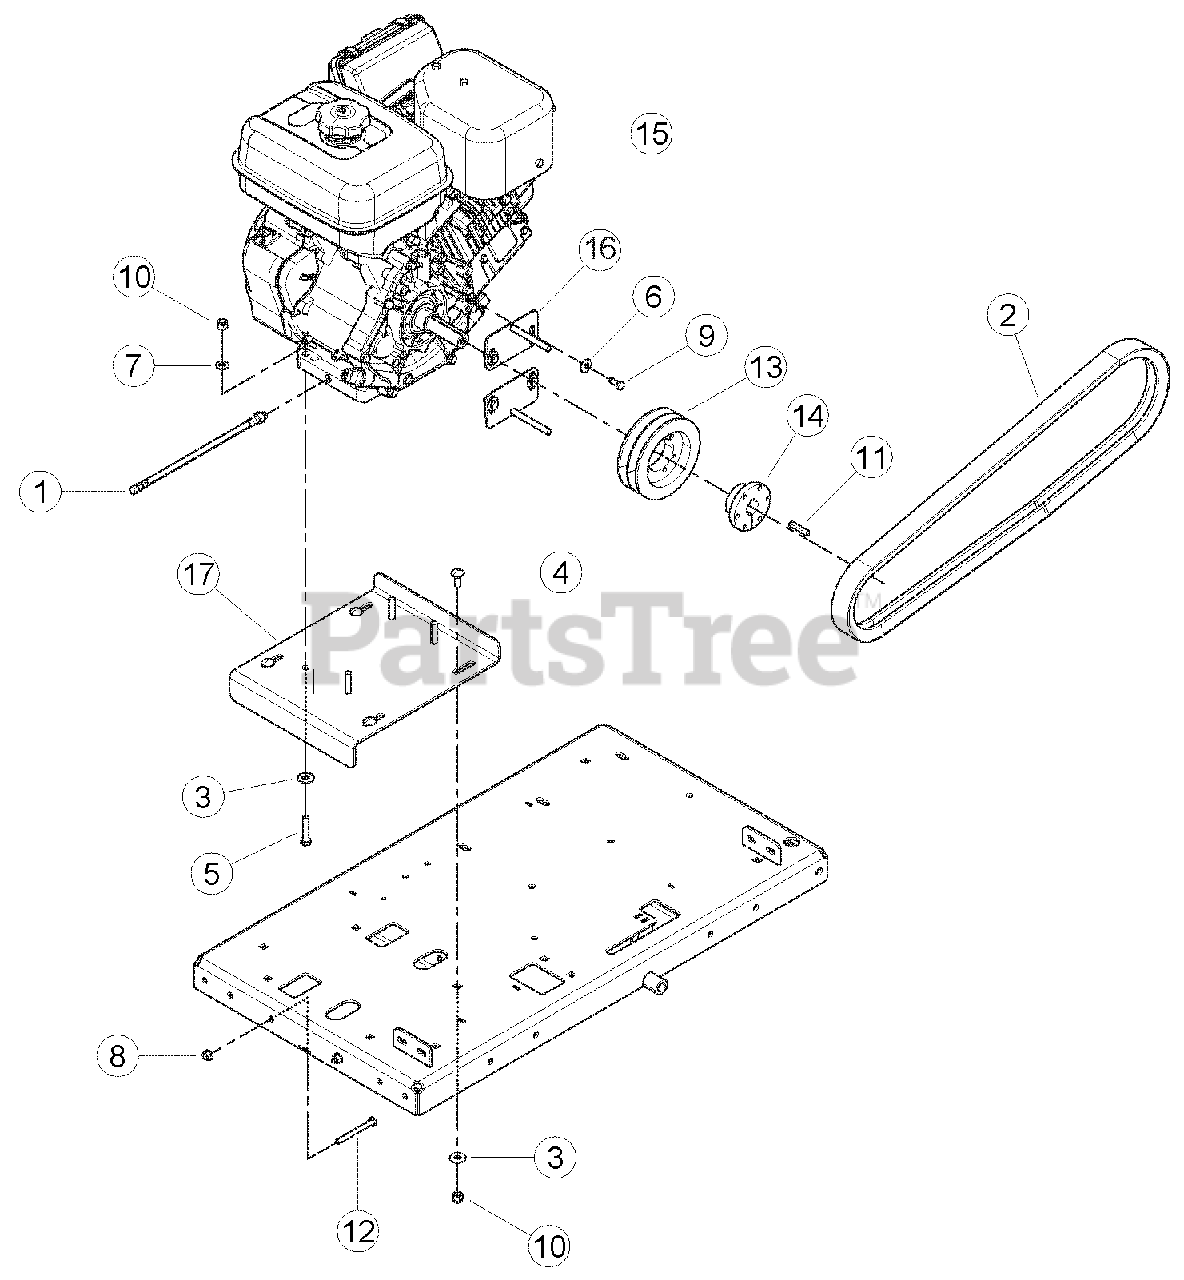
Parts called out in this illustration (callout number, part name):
1	HOSE ASSY, CRANKCASE DRAIN
2	BELT, 2RB61 ARAMID
3	WASHER, 3/8 FLAT ZP
4	BOLT, 3/8 X 1 CRG GR5 NC ZP
5	BOLT, 3/8 X 1-3/4 HCS GR5 ZP
6	WASHER, 5/16 FLAT ZP
7	WASHER, 3/8 SAE FLAT ZP
8	NUT, 5/16 SERR FLANGE NC ZP
9	BOLT, 5/16-24 X 3/4 HHCS GR5 ZP
10	NUT, 3/8 NE NYLOCK ZP
11	KEY, 1/4 SQUARE X 1-1/2 LONG PLAIN
12	BOLT, 5/16 NC X 3 FULL THD (CH4400)
13	SHEAVE, 2B5.2 SDS
14	BUSHING, SDS 1"
15	ENGINE, SUBARU EX40 404CC (FOR SERVICE SEE ENGINE OWNERS MANUAL OR YOUR NEAREST SUBARU INDUSTRIAL ENGINE DEALER.)
16	GUIDE, BELT
17	PLATE, ENGINE
